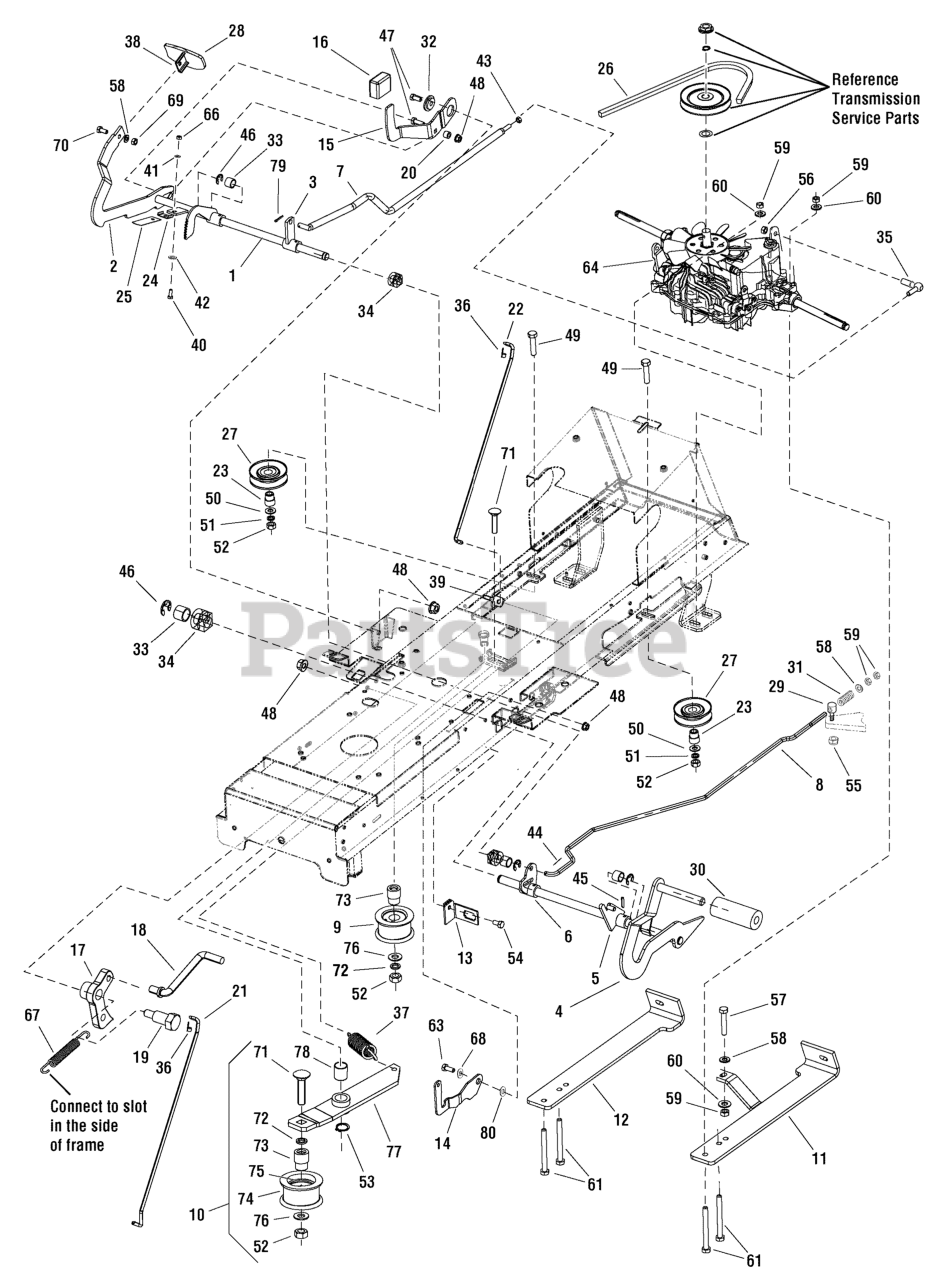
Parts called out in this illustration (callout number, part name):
1	PEDAL, Forward
4	PEDAL, Brake
5	LEVER, Parking Brake
6	LEVERe, Brake
7	ROD, Traveling
8	ROD, Brake
9	PULLEY, Tensioning
10	PULLEY, Idler
11	HOLDER, Left
12	HOLDER, Right
13	SUPPORT, Switch
14	LATCH, Brake Lock
15	PEDAL, Reverse
16	PAD, Foot Pedal
17	LATCH, Cruise
18	ROD, Cruise 5/16 dia. x 2.83"
19	BOLT, Shoulder, 5/16-18 x 1-5/8
20	SPACER, Foot Pedal
21	ROD, Cruise, Latch, Upper
22	ROD, 1/4 dia x 15.95"
23	BUSHING, 0-9421-418
24	WASHER, Lock
25	SPRING, Flat 0-9740-221
26	V-BELT, 13 x 2580 Li BBT
27	PULLEY, Compensa C-00237/1
28	PEDAL, Forward Rubber
29	BOLT, 0-9016-447
30	PEDAL, Brake Pad
31	SPRING, TLZ 250.150.0530 Yellow
32	SPACER, Pivot
33	DISTANCE, Pedal 0-9521-288
34	BUSHING, 0-9462-202
35	BALL JOINT, CS 13 DIN 71802 M8 Silver
36	CLIP LINKAGE, 1/4 dia
37	SPRING, TZ 2x14 x 62 Yellow
38	PEDAL, Forward Top
39	BOLT, Eye M6 x 80 BN1006
40	BOLT, M6 x 16
41	Washer 6.4
42	WASHER, 6
44	SPINDLE, 2 x 20
45	PIN, Flex 5 x 25
46	LOCK RING, 12
47	BOLT, Carriage, 5/16-18 x 1 1/4
48	NUT, Hex Flange, 5/16-18 x 1-5/8
49	BOLT, M10 x 40
50	WASHER, 10.5
51	WASHER, 10
52	NUT, M10
53	LOCK RING
54	SCREW, Tap 5/16-18 x 5/8
55	NUT, M10
57	BOLT, M8 x 45
58	WASHER, 8.4
60	WASHER, 8
61	BOLT, M8 x 75
63	BOLT, Shoulder, 5/16-18 x 15/32
64	TRANSMISSION, Tuff Torq, K46CW
68	WASHER, 14 x 26/0.2
70	BOLT, M8 x 20
71	SCREW, M10 x 45
72	LOCK RING, 40
73	BUSHING, Pulley, Tension
75	BALL BEARING, Pulley
76	WASHER, 11
77	ARM, Pulley, Tension
78	BEARING, Slide
